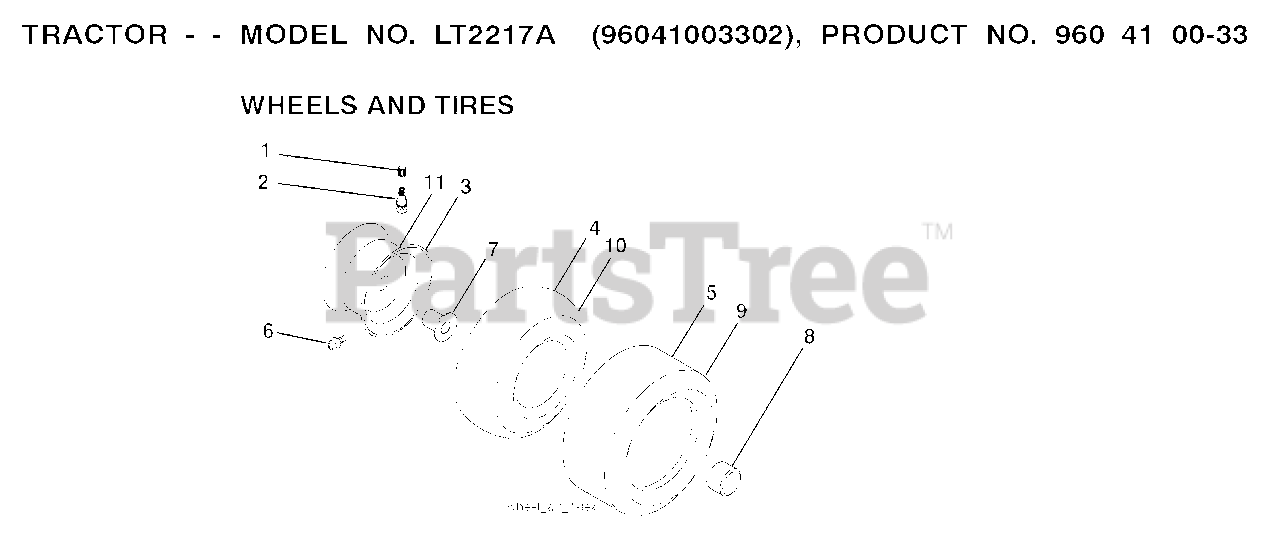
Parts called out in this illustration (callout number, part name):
1	VALVE CAP
2	VALVE STEM LT
3	RIM ASM 6" FRONT SILVER
4	TUBE.5.3/4.5/6
5	TIRE HEAVY DUTY
6	FITTING LT
7	BEARING T
8	CAP, AXLE BLK
9	TIRE HEAVY DUTY
10	TUBE
11	RIM ASM 8" REAR SILVER
